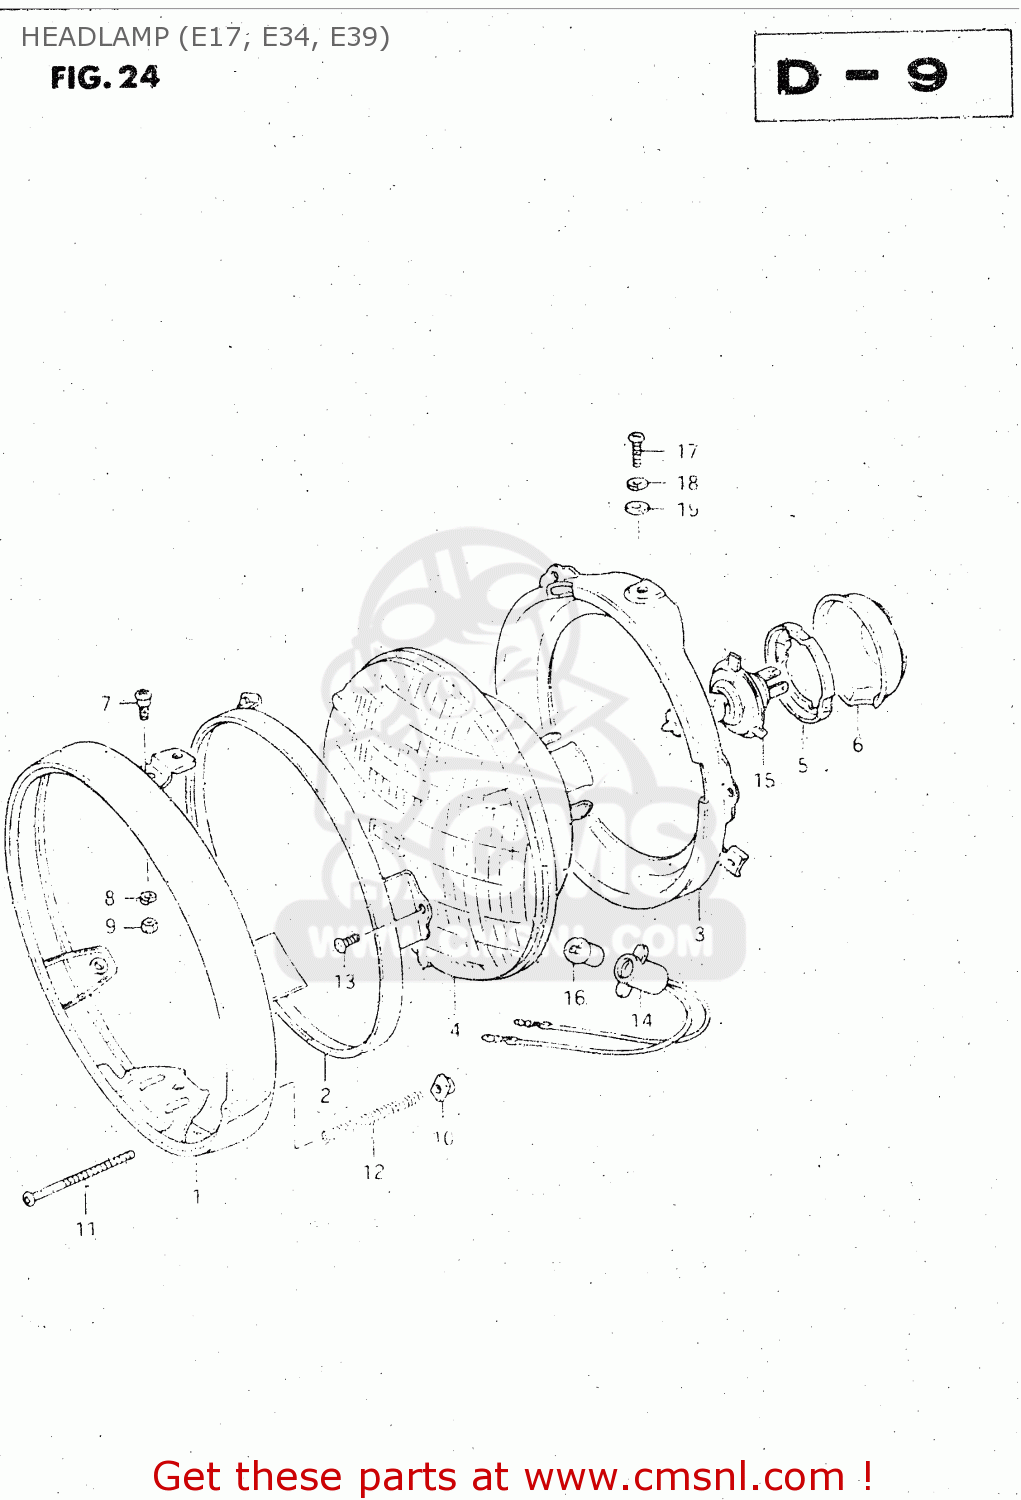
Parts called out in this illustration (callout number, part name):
1	RIM
2	RETAINING RING
3	RING
4	UNIT,HEAD LAMP
5	SETTING,BULB
6	COVER,HEADLAMP SOCKET
7	H/LAMP LENS UNIT FITING SCRE
8	LOCK WASHER
9	NUT
10	NUT
11	SCREW
12	SPRING,ADJUSTING
13	SCREW
14	SOCKET
15	BULB(12V60/55W,H4)
16	BULB(12V4W)
17	SCREW
18	WASHER,LOCK
19	WASHER
